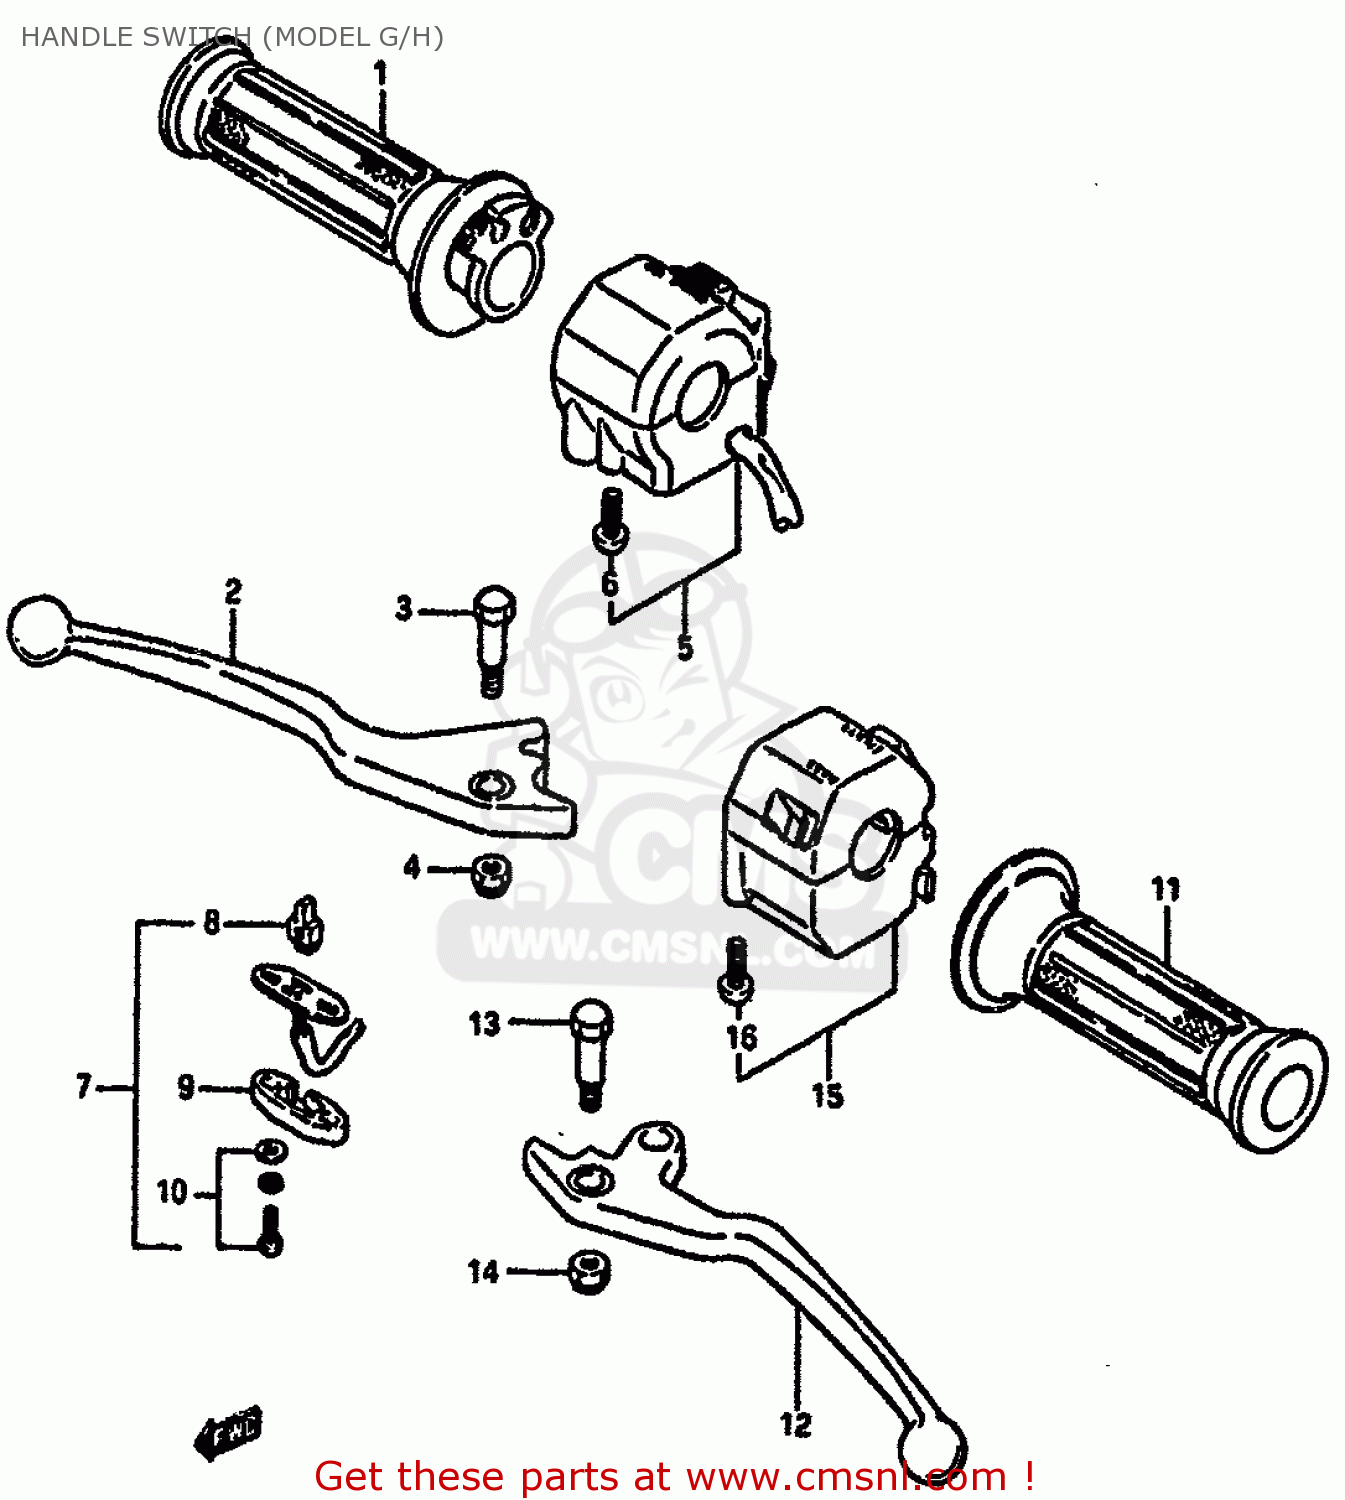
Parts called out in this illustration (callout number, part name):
1	GRIP,THROTTLE
2	LEVER,BRAKE
3	BOLT,LEVER
4	NUT
5	SWITCH ASSY,R
6	SCREW, 5X45
7	SWITCH ASSY,STOP
8	CONTACT,SWITCH
9	COVER,FR BK TERMINAL BASE
10	SCREW
11	GRIP,L
12	LEVER,CLUTCH (BLACK)
13	BOLT,LEVER
14	NUT
15	SWITCH ASSY, HANDLE LH
16	SCREW
